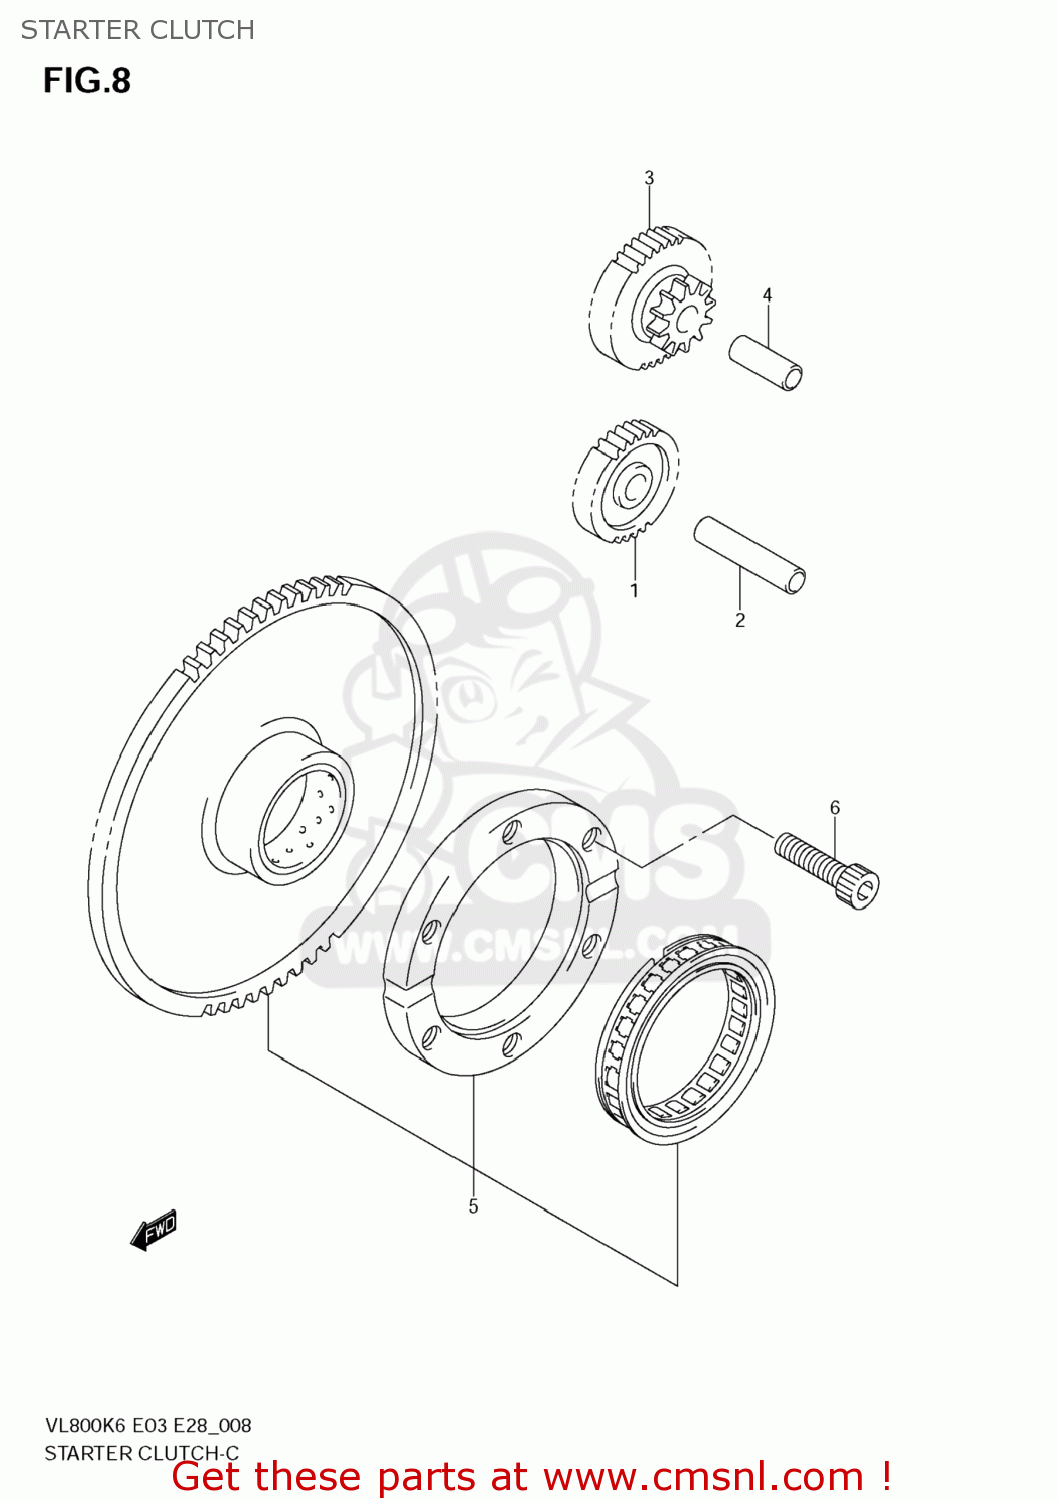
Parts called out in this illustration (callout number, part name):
1	GEAR,STARTER IDLE NO.1
2	PIN,10X43
3	GEAR,STARTER IDLE NO.2
4	PIN
5	CLUTCH SET,STARTER
6	BOLT(8X30)
